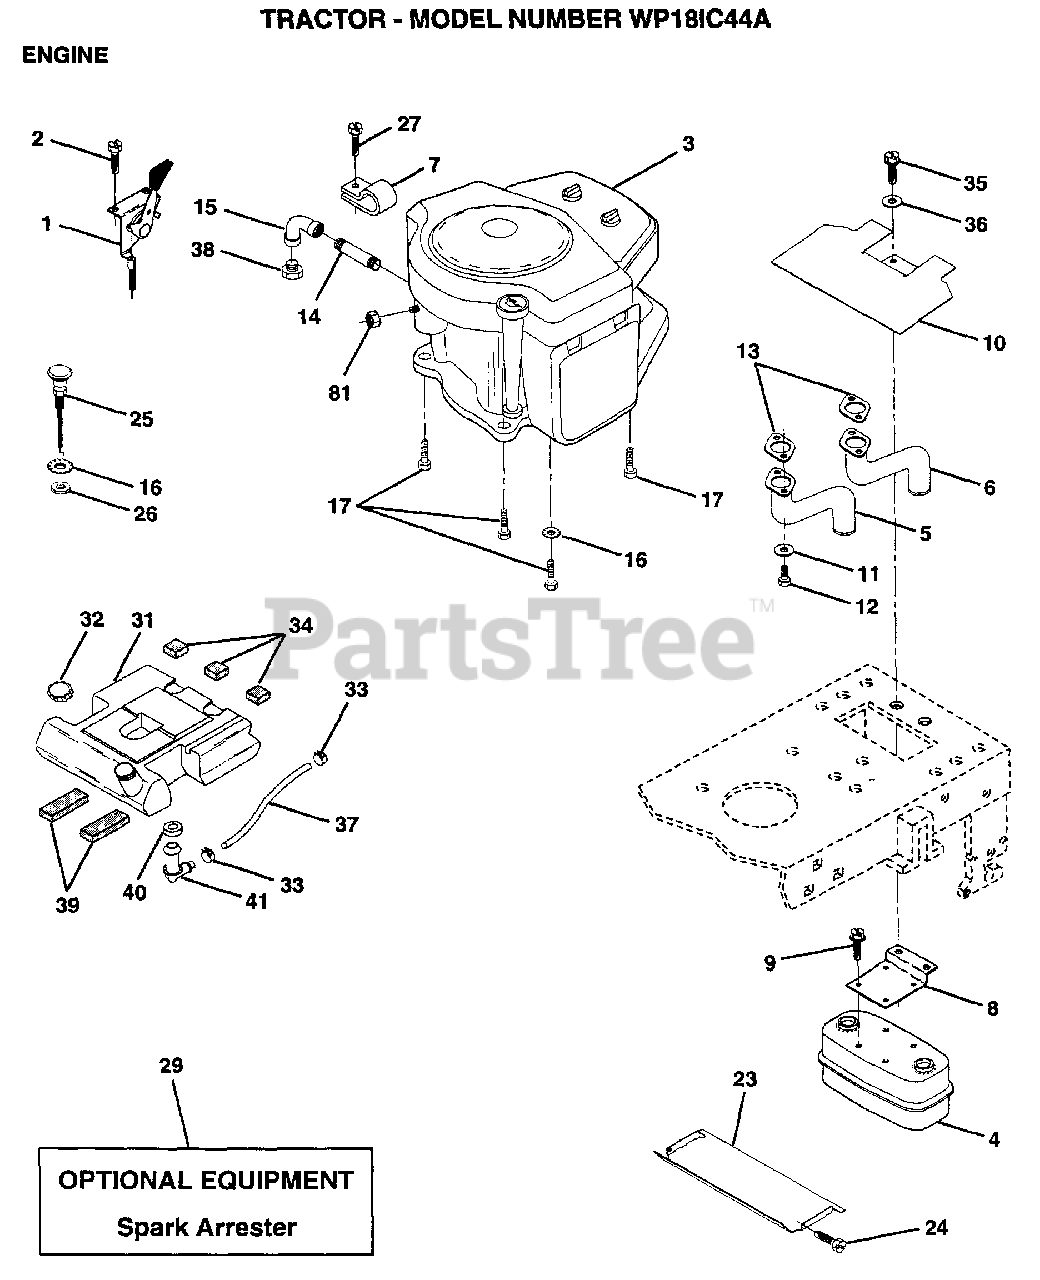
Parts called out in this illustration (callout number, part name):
2	SCREW LT
3	ENGINE B&S 18HP
5	EXHAUST.B&S.18.LH
6	EXHAUST.B&S.18.RH
7	CLAMP.TUBE.DBL.EN
8	BRACKET MUFFLER
9	SCREW ST
10	SHIELD.HEAT.
11	LOCKWASHER
14	PIPE NIPPLE LT
15	ELBOW
16	LOCKWASHER
17	SCREW LT
23	HEAT SHIELD
24	SCREW
25	"CONTROL.CHOKE.51"""
27	SCREW LT
32	CAP ASM FUEL
33	HOSE CLAMP
34	PAD-SPACER LT
35	SCREW
36	WASHER
37	FUEL LINE T
39	PAD IDLER TI
40	BUSHING OUTLET T
41	STEM.TANK.FUEL
81	NUT
